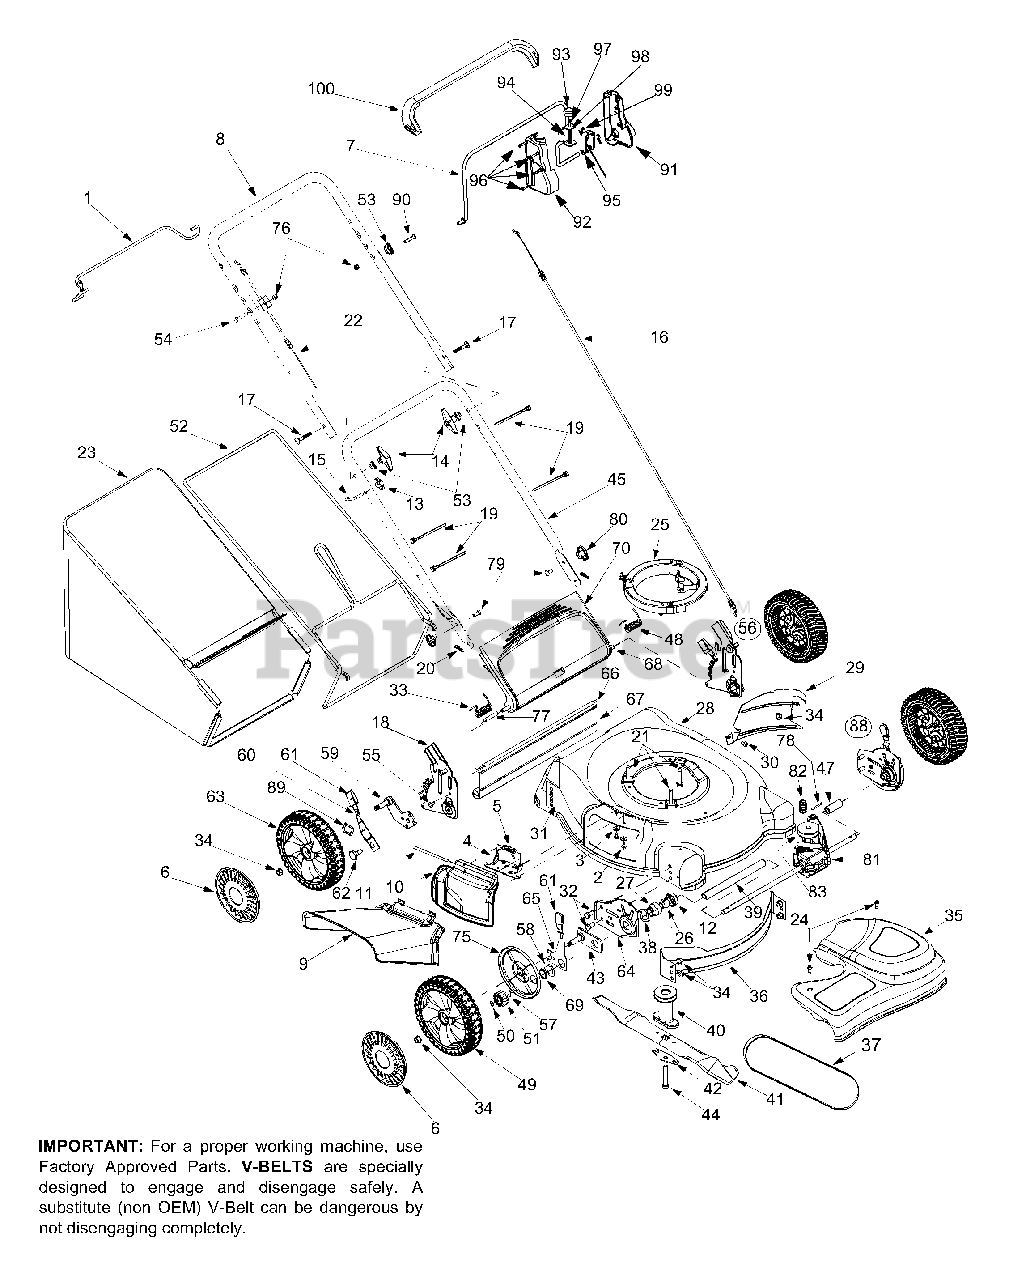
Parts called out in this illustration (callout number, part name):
2	TT Screw 1/4-20 x 0.5
3	Bell Washer.265 x 0.75
4	Deflector Chute Adapter
5	Torsion Spring
6	Hub Cap
10	Mulch Plug Complete
11	Hinge Pin
12	Bearing Retainer
13	Handle Knob
14	Handle Knob
15	Eye Bolt
16	Control Cable - 58.25"
17	Carriage Bolt 5/16-18 x 2.0
18	RH Handle Bracket
19	Cable Tie
20	Cotter Pin
21	Self-Tapping Sems Screw
22	Drive Cable
23	Grassbag Assembly
24	Shoulder Screw # 12 -24
25	Engine Spacer
26	Bearing Sleeve
27	Bearing Support
28	21" Deck
30	Screw AB: 1/4-14:.625
32	Hex Screw 3/8-16 x.75
33	Torsion Spring RH
34	Flange Lock Nut 3/8-16
35	Transmission Cover (Yellow)
38	Wave Washer
39	Sleeve Spacer 9.04" Lg.
40	Blade Adapter w/ Pulley
41	21" Mulching Blade
42	Blade Bell Support
43	Pivot Plate Assembly
44	Hex Screw 3/8-24 x 2.50
47	Slev. Spacer 2.1" Lg.
48	Torsion Spring LH
49	Front Wheel
50	Snap Ring
51	Gear 14T RH FWD
53	Saddle Washer
54	Hex Screw 1/4-20 x 1.50
55	TT Scr. w/Washer 1/4-20 x.625
56	RH Handle Bracket Assembly
57	Dowel Pin
58	Washer
59	Pivot Arm Assembly - RH
60	Rear Spring Lever
61	Spring Lever Knob
62	Shoulder Scr.500 Dia. x.434
63	Rear Wheel
66	Wire
67	Rear Trailing Shield
68	Pivot Rod
69	Snap Ring
70	Rear Discharge Door
75	Wheel Dust Cap
76	Hex Lock Nut 1/4-20
77	Spacer.375 x.50 x 1.02" Lg.
78	Roll Pin
79	Carriage Bolt 1/4-20
80	Wing Nut
81	Transmission Assembly
82	Belt Tension Spring
83	Input Pulley
88	Height Adjustment Assembly RH
89	Wave Washer
90	Hex Hd. Cap Screw
91	Control Lever LH
92	Control Cover RH
93	Button
94	Compression Spring
95	Lever
96	Hi-Low Screw
98	Retention Ring
99	Torsion Spring
100	Deluxe Bail Cover
